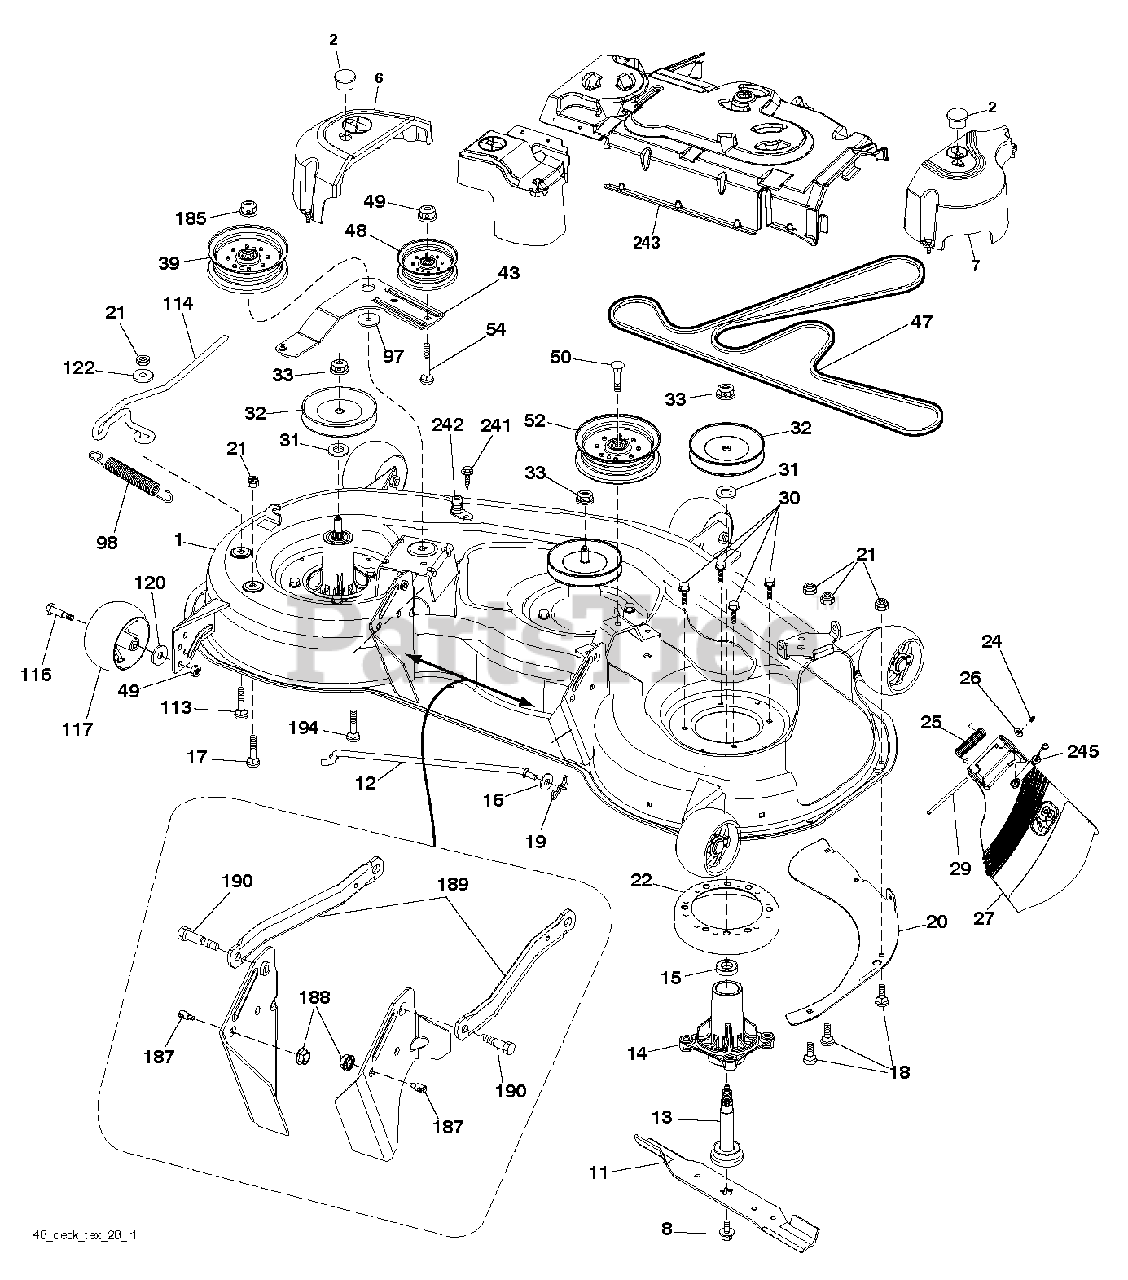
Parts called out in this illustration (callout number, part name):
1	DECK.WELDMENT.54'
6	COVER.MANDREL.LH.54"20
7	COVER.MANDREL.RH.54.20
8	BOLT.WASHER.ASM.7/16-2
12	ROD.ANTI.SWAY.48/54"TE
13	SHAFT ASM MANDREL
14	HOUSING.MANDREL.4PT.
16	WASHER
17	BOLT
18	BOLT
19	PIN.COTTER.5/16.BOW TI
20	BAFFLE, VORTEX MWR
21	LOCKNUT
22	STRIPPER.MANDREL.ROUND.BLACK
24	CAP-SLEEVE LT
25	SPRING, TORSION
26	NUT PUSH M
29	ROD.HINGE
30	SCREW, WASHER HEAD
31	WASHER.SPACER.MANDREL
32	PULLEY/MANDREL
33	NUT.FLANGE.LOCK.TOP
39	RB PULLEY.IDLER.4.50/HUB SPEC
46	SCREW.1/4-20X5/8
47	BELT.DRIVE.54."2006
48	PULLEY.IDLER.48"PRIMARY
49	NUT LOCK FLG 3/8-16 UNC
52	PULLEY.IDLER.2006
54	BOLT.3/8-16X1.50
98	SPRING, DECK DRIVE
114	ROD TENSION RELIEF
116	BOLT.SHOULDER.3/8-16X3-5/8.
117	WHEEL. GUAGE RALLY
120	WASHER
122	BUSHING.RELIEF.TENSION
185	NUT.LOCK.FLANGE.7/16
187	STUD.FASTNER.W/ANTI-ROTATE
188	NUT LOCK HEX FLANGE 5/16-18
189	ARM.SUSPENSION.MOWER
190	BOLT.SHOULDER
192	KEEPER.BELT.IDLER.54"T
194	BOLT.HEX.WASHER.HEAD.7/16-24X
241	SCREW.TT.#10-32X.5.3/8.FLANGE
242	PORT.WASHOUT
245	ELASTIC STRAP KIT
